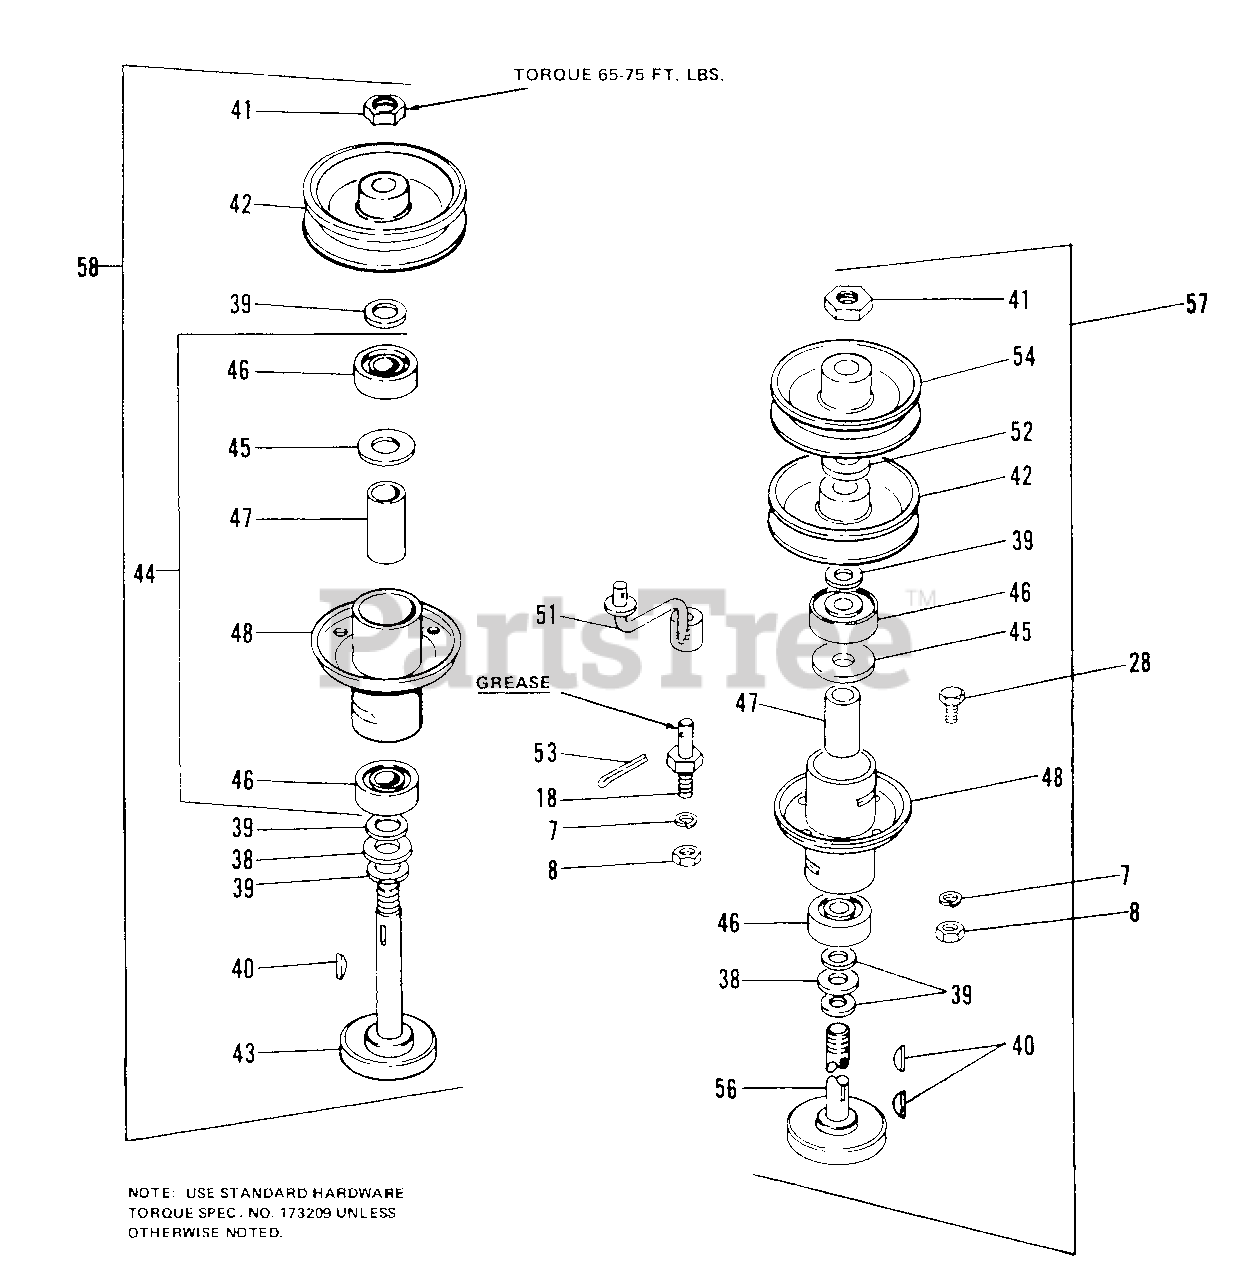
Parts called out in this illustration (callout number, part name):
7	LOCKWASHER, Spring, 5/16
8	NUT, Hex, 5/l6-18
18	PIN, Pivot
28	CAPSCREW, Hex Hd., 5/16-18 x 3/4
40	KEY, Woodruff. No. 61
41	NUT, Flex Lock, 3/4-16
43	ARBOR ASSY, Side
44	TUBE & ARBOR ASSY, w/Bearings
45	RING, Backing
46	BEARING, Ball
48	TUBE & ARBOR ASSY
51	BAR ASSY, Brake
52	WASHER, Plain, 3/4
53	PIN, Cotter, 3/32 x 3/4
54	PULLEY, Drive
56	ARBOR, Center
57	ARBOR KIT, Center
58	ARBOR KIT, Outside
